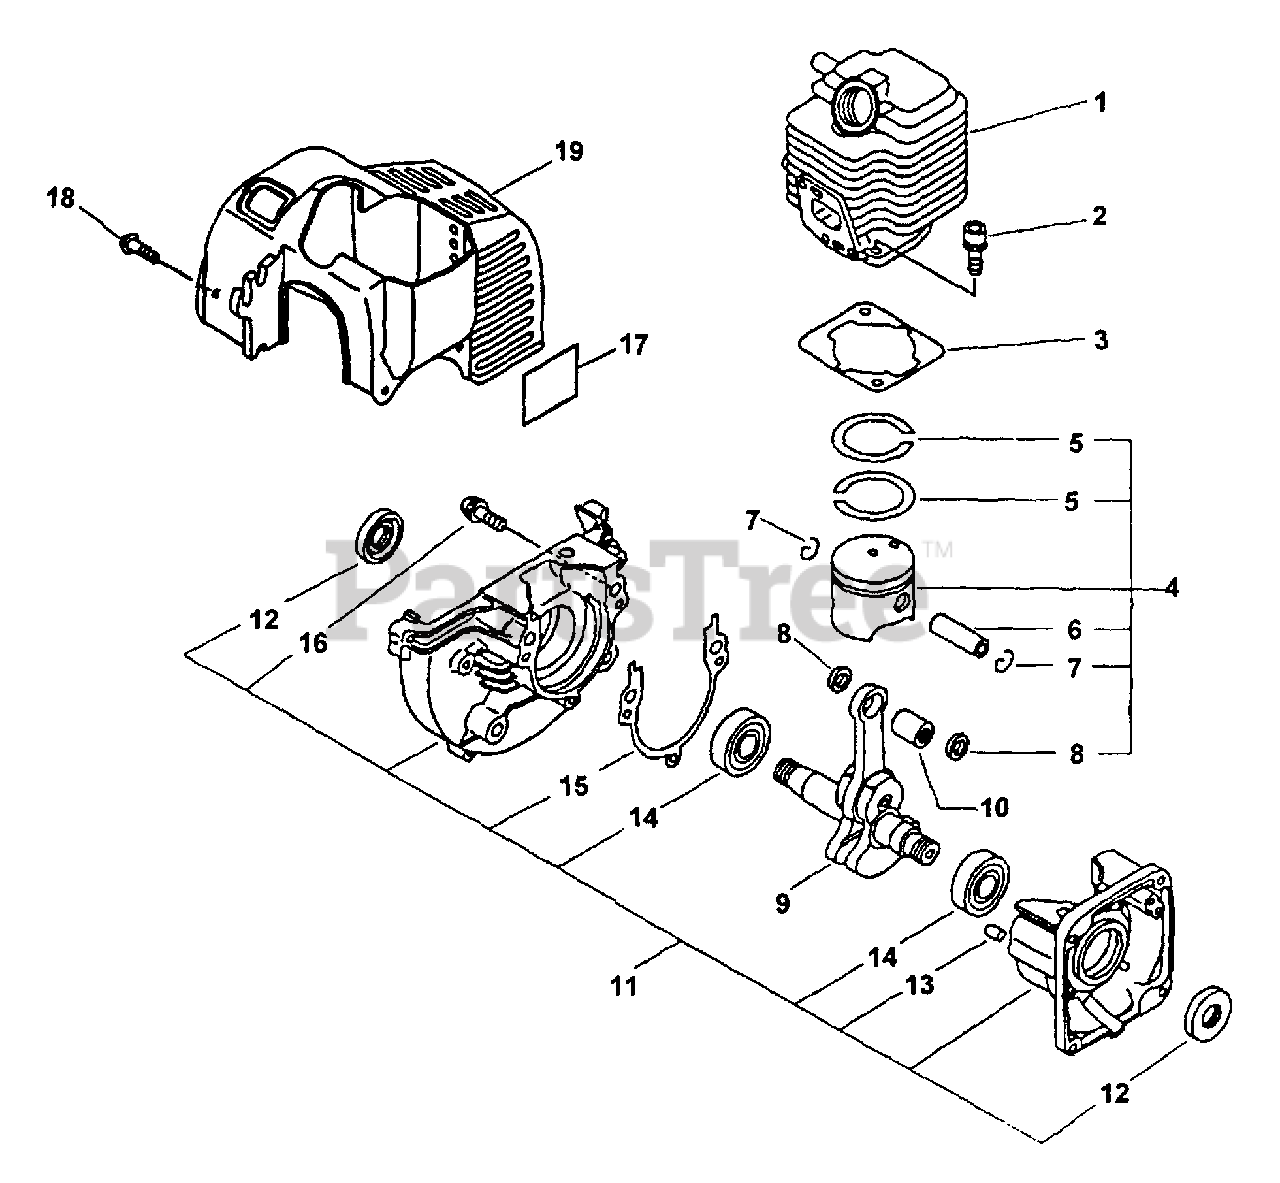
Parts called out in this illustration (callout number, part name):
1	CYLINDER
2	BOLT 5×22
3	GASKET, CYLINDER
4	PISTON KIT
5	RING, PISTON
6	PIN, PISTON 8
7	RING, SNAP
8	WASHER, THRUST
9	CRANKSHAFT ASSY
10	BEARING, NEEDLE
11	CRANKCASE KIT
12	SEAL, OIL 12
13	PIN, LOCATING 4
14	BEARING, BALL - 6201 C3
15	GASKET, CRANKCASE
16	BOLT 5×28
17	LABEL, EDR-2100
18	SCREW 4×12
19	COVER, ENGINE - GRAY
